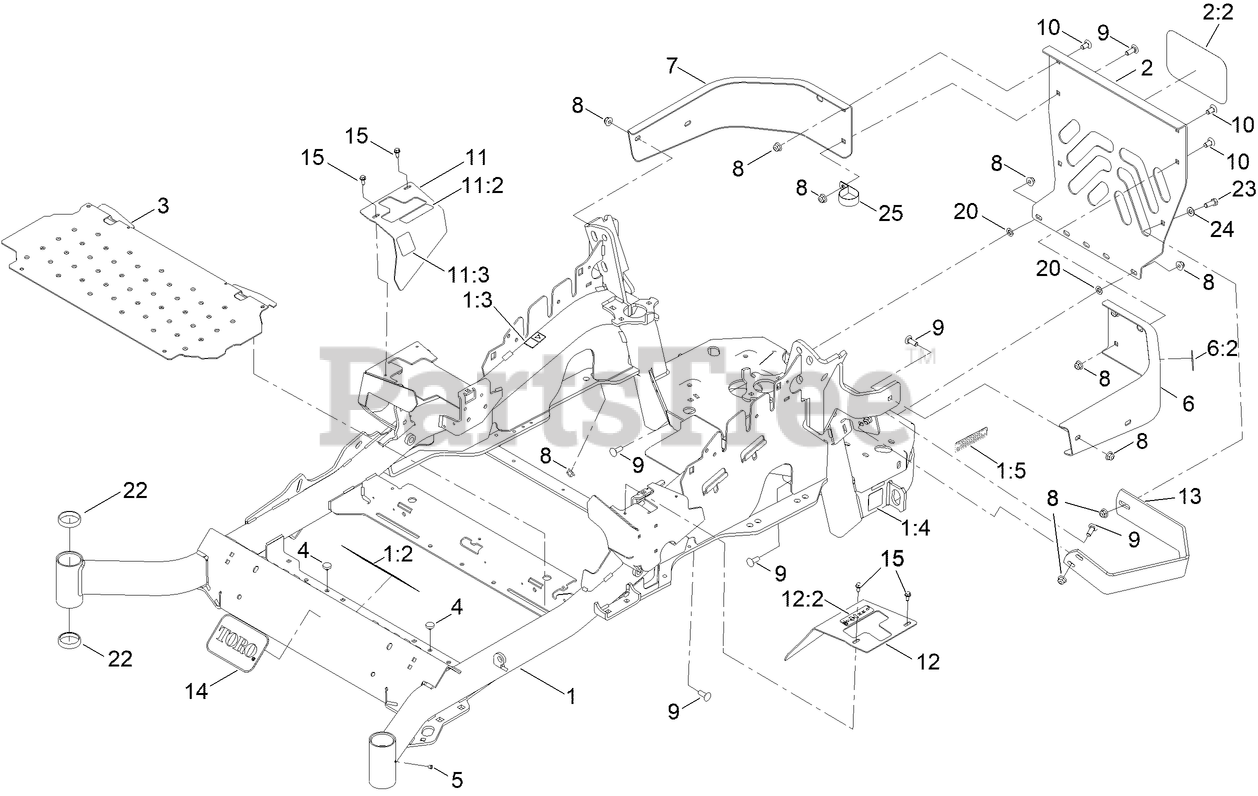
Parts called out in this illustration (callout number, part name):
1	MAINFRAME SERVICE ASM - 60
1:2	DECAL-DANGER
1:3	DECAL-WARNING
1:4	DECAL-HAZARD, PINCHED FINGER
1:5	DECAL-ARRESTOR, SPARK
2	REAR GUARD ASM
2:2	DECAL
3	FLOORPAN
4	BUMPER
6	LH BUMPER ASM
6:2	DECAL-WARNING
7	BUMPER-RH
8	NUT-HF, NI
9	SCREW-CARR
10	SCREW-CARR
11	RH MOTION CONTROL COVER ASM
11:2	DECAL-CONTROL, MOTION
11:3	DECAL-PARK BRAKE, CE
12	LH MOTION CONTROL COVER ASM
12:2	DECAL-CONTROL, MOTION
13	GUARD-MUFFLER
14	DECAL
15	SCREW-HWH
20	NUT-PUSH
22	CUP-BEARING
23	SCREW-HH
24	WASHER-FLAT
25	CLAMP-R
